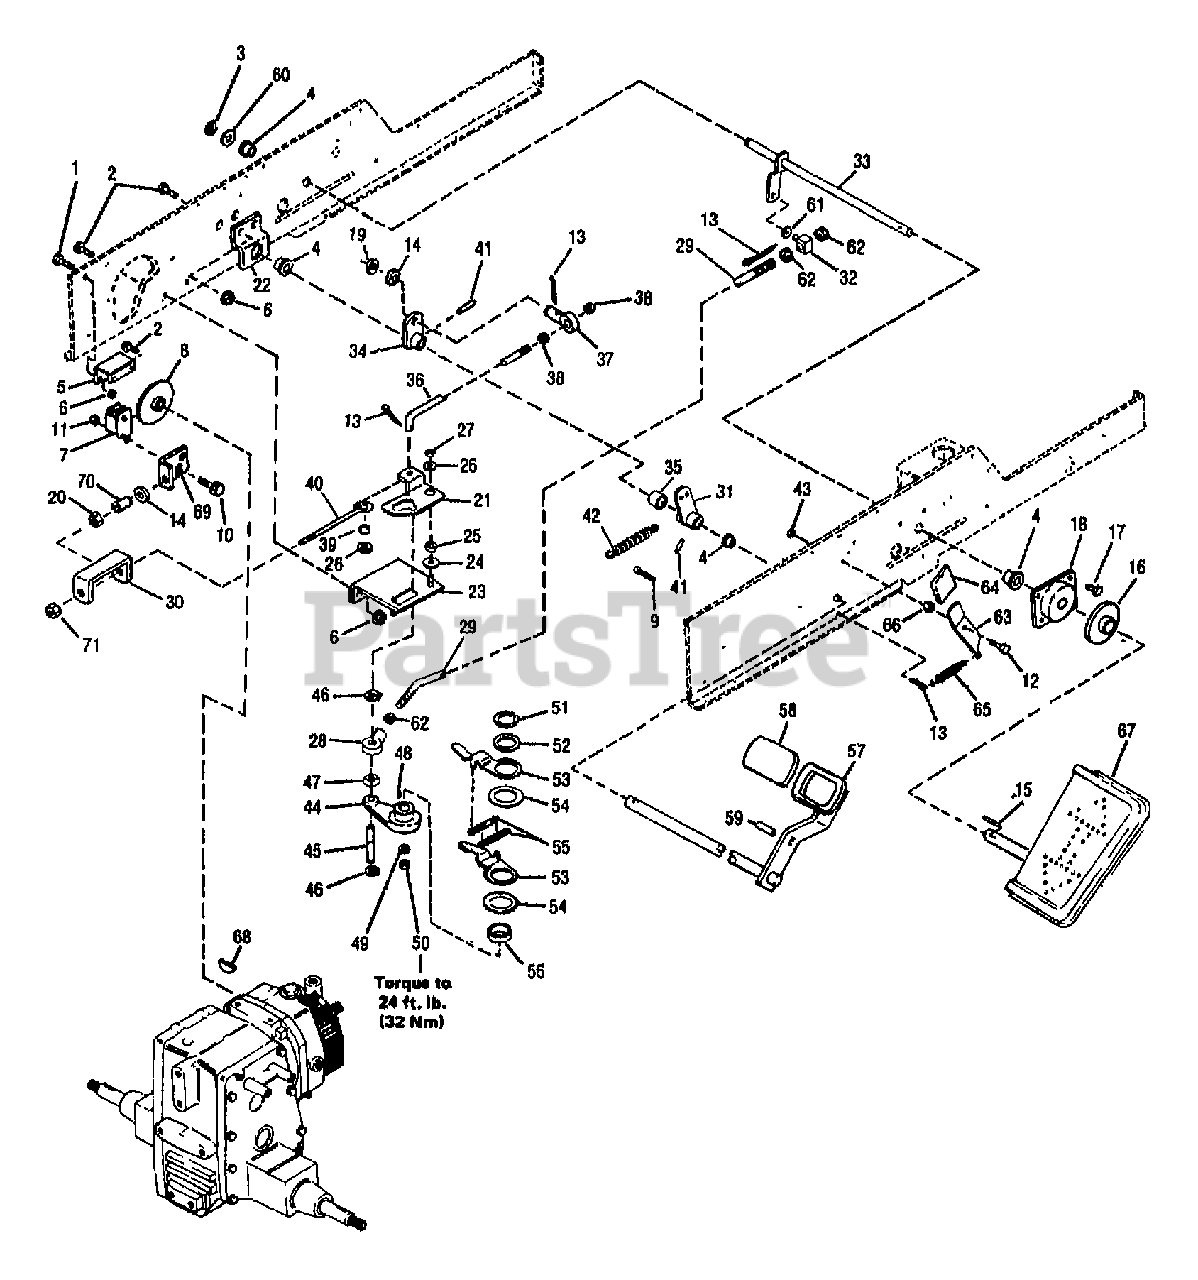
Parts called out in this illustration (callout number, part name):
1	SCR-HFLK 3/8-16X1.00 ZP
3	RING-RETAIN .625 ID
4	BEARING-FLANGE
5	BRKT-TRANSAXLE
6	NUT-HFLK 3/8-16 ZP
7	KIT-BRAKE
8	BRAKE-DISC
9	PIN-COTTER .120X1.00 ZP
10	SCR-HH 1/4-20X.75 G5 ZP
11	NUT-HF/LK 1/4-20 ZP
12	SCR-HFLK 3/8-16X1.25 ZP
13	PIN-COTTER .09X.75 ZP
14	WASHER-FLAT 5/16 SAE
15	PIN-ROLL
16	ASSM-CONTROL DISC
18	CLUTCH
19	WASHER-.632X.39X.0329
20	NUT-HEX 5/16-18 ZP
21	PLATE-NEUTRAL
22	BRKT-BRAKE SHAFT
23	PLATE-NEUTRAL
24	WASHER-1.75X.39X.059
25	SPACER-.625X.4X.2
26	WASHER-FLAT 3/8 SAE
27	NUT-H/LK 3/8-16
28	ROD-END
29	ROD-SPEED CONTROL
30	BRAKE-RETURN
31	ASSM-BRAKE ARM
32	SWIVEL
33	ASSM-SHAFT SPEED CONTROL
34	ASSM-ARM
35	SPACER-.875X.685X.25
36	ROD-BRAKE CONTROL
37	SWIVEL
38	NUT-HEX/JAM 3/8-16
39	SPACER
40	ROD-BRAKE
41	PIN-DRIVE .187X1.0
42	SPRING-EXTENSION
43	NUT-LOCK 3/8-16
44	ARM-SPEED CONTROL
45	PIN-CONTROL
46	RING-RET.EXT .437 ID
48	KEY-WOODRUFF 1/8 X 5/8
49	WASHER-1.06X.531X.1 ZP
50	NUT-H/LK 1/2-13
51	RING-RET
52	WASHER
54	WASHER-THRUST
55	SPRING
56	BEARING
57	ASSM-BRAKE PEDAL
58	PAD-PEDAL
59	PIN-ROLL .188X.75
60	WASHER-1.115X.637X.06
61	WASHER-.632X.39X.0329
62	NUT-HEX/JAM 7/16-20
63	LOCK-BRAKE
65	SPRING
66	NUT-JAM
68	KEY-WOODRUFF .25X.75
69	EXT-BRAKE ARM
70	SLEEVE
71	NUT-H/LK 5/16-18
